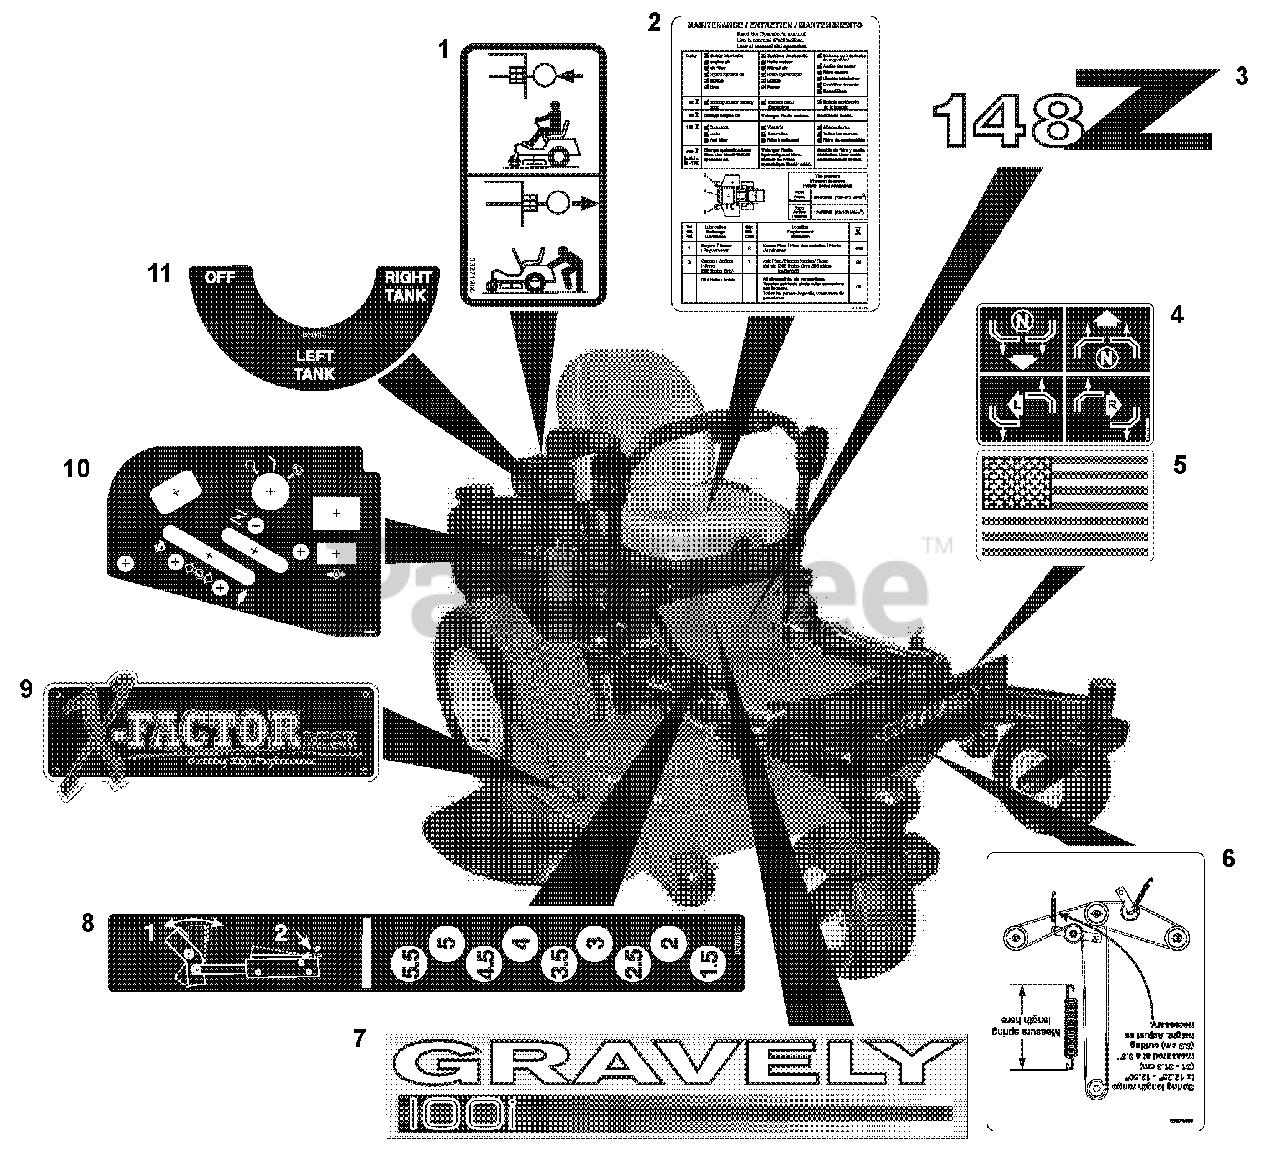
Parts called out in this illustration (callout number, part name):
1	Decal, Transmission Disconnect
2	Decal, Maintenance Instructions
3	Decal, Logo- Gravely 148Z (060)
4	Decal, Instructional- Steering
5	Decal, American Flag
6	Decal, Belt Routing
7	Decal, 100I
8	Decal, Height of Cut
9	Decal, X-Factor Deck
10	Decal, Control Panel
11	Decal, Fuel Valve
